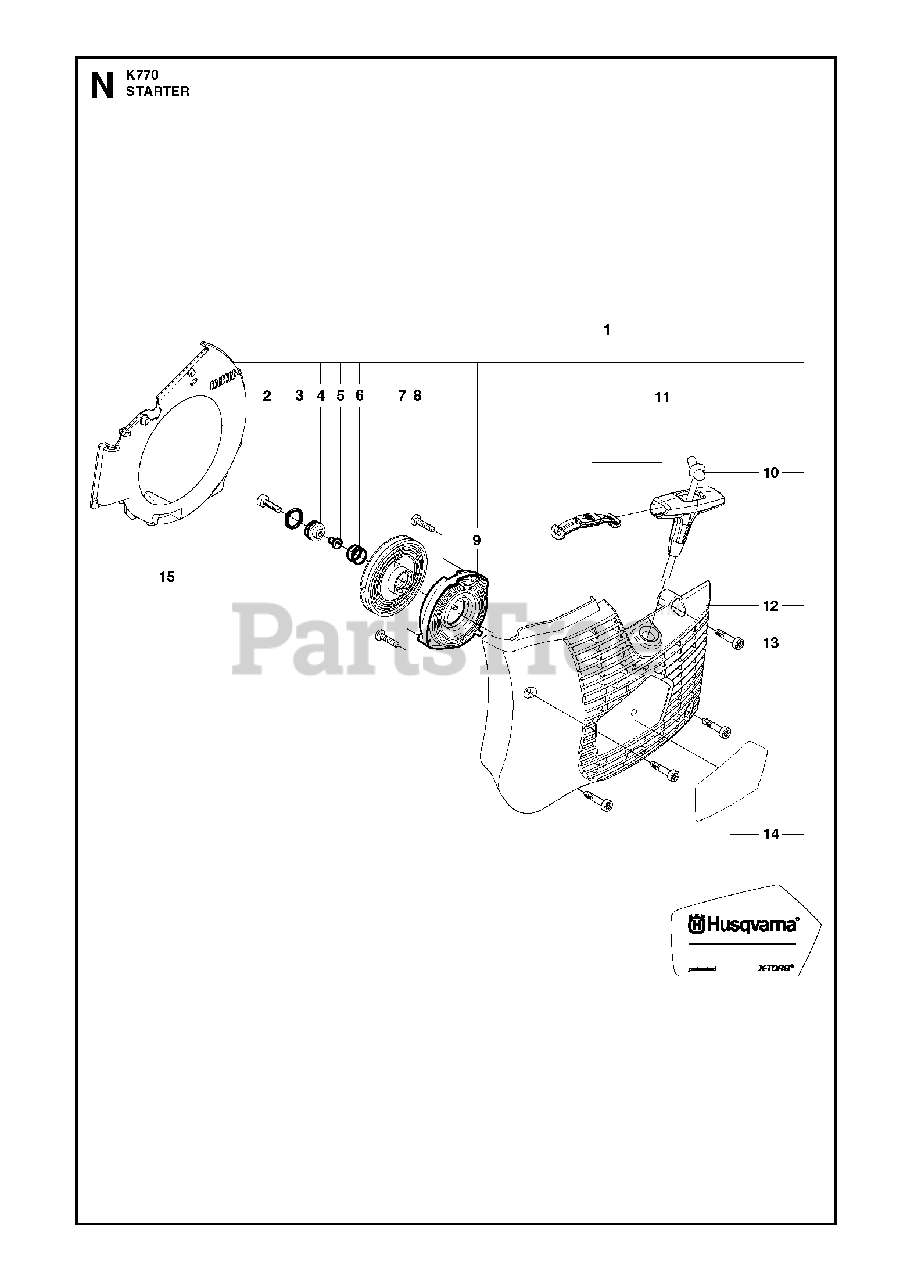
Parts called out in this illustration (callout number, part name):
2	SCREW ITXSCT
5	SPACING SLEEVE
6	COMPRESSION SPRING
7	STARTER PULLEY
8	SCREW CITXPANT
9	RECOIL SPRING
10	STARTER CORD50 m
11	STARTER HANDLE ASSY
12	STARTER COVER
13	SCREW ITXSCM
15	COOLING AIR CONDUCTOR
